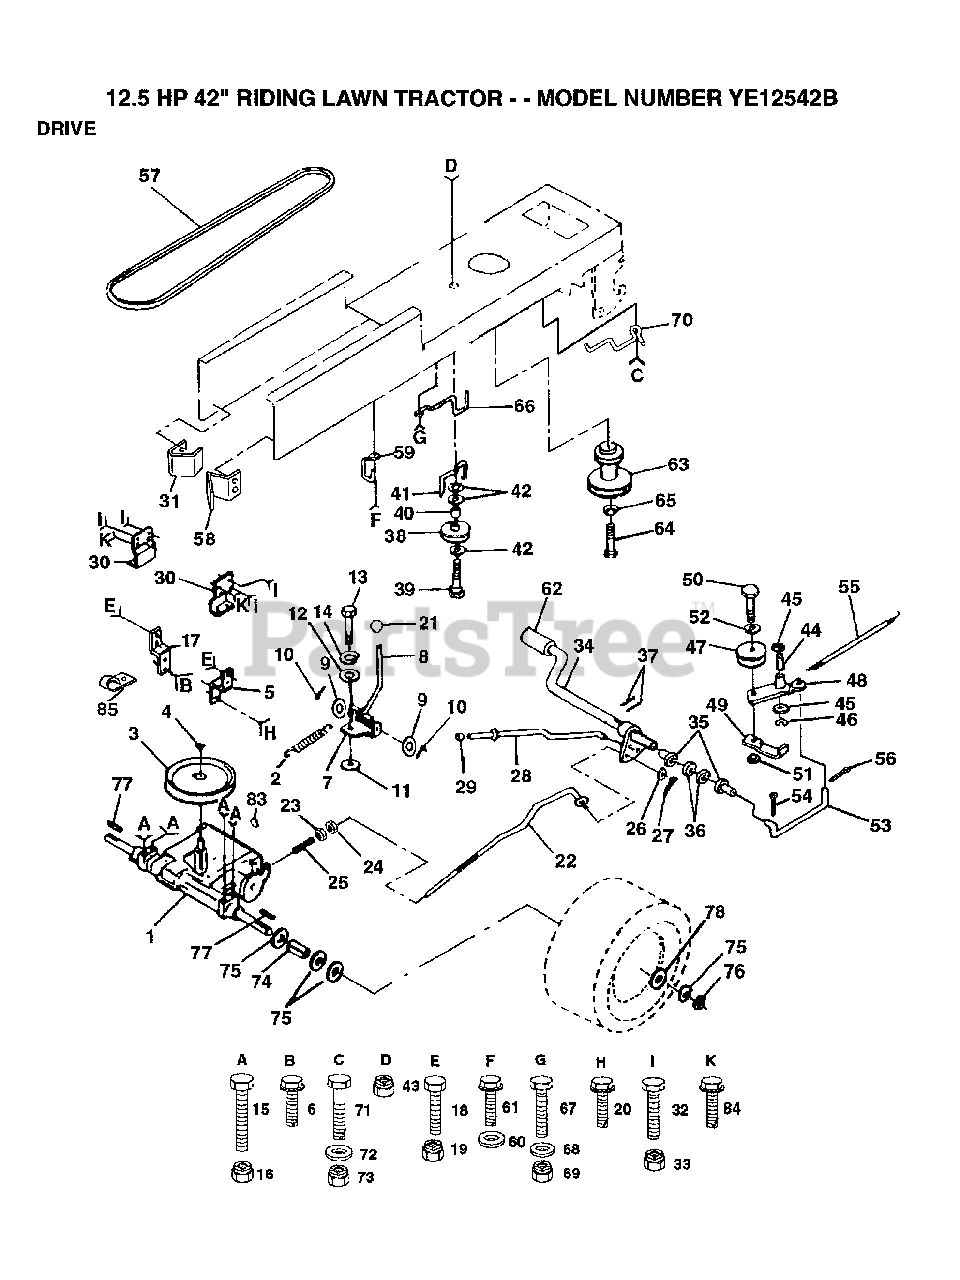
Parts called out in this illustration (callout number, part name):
3	PULLEY TRANS
5	STRAP TORQUE
6	SCREW
8	SHIFT ROD
9	WASHER
10	PIN COTTER 1/8
11	WASH-SHFT PLT LT
12	WASHER LT
14	LOCKWASHER
15	BOLT
17	STRAP TORQUE
20	SCREW
21	KNOB.DUCKHEAD.1/2
22	BRAKE ROD
23	NUT
24	NUT
25	SPRING ROD LT
26	WASHER
27	COTTER PIN
28	BRAKE PARK ROD
29	PLUNGER CAP T
30	TRANSAXLE MTG BKT
31	"KEEPER,BELT LH T"
32	BOLT
35	NYLON BEARING
36	WASHER LT
38	PULLEY.IDLER.FLAT
39	BOLT
40	SPACER T
41	BELT KEEPER LT
42	WASHER
44	"LY, BEARING"
45	WASHER LT
46	KLIP RING
48	ARM IDLER
49	RETAIN BELT
52	WASHER
53	"LINK, CLUTCH T"
54	COTTER PIN
55	"SPRING, RETURN LT"
56	COTTER PIN
58	"KEEPER,BELT RH T"
60	WASHER
61	SCREW
62	PEDAL COVER T
64	BOLT
65	LOCKWASHER
66	KEEPER.BELT.ENG.L
67	BOLT
68	WASHER
70	KEEPER BELT ENG
71	BOLT
72	WASHER
74	SPACER LT
75	WASHER
76	E-RING LT
77	SQUARE KEY
78	WASHER
84	SCREW
85	CLIP T
